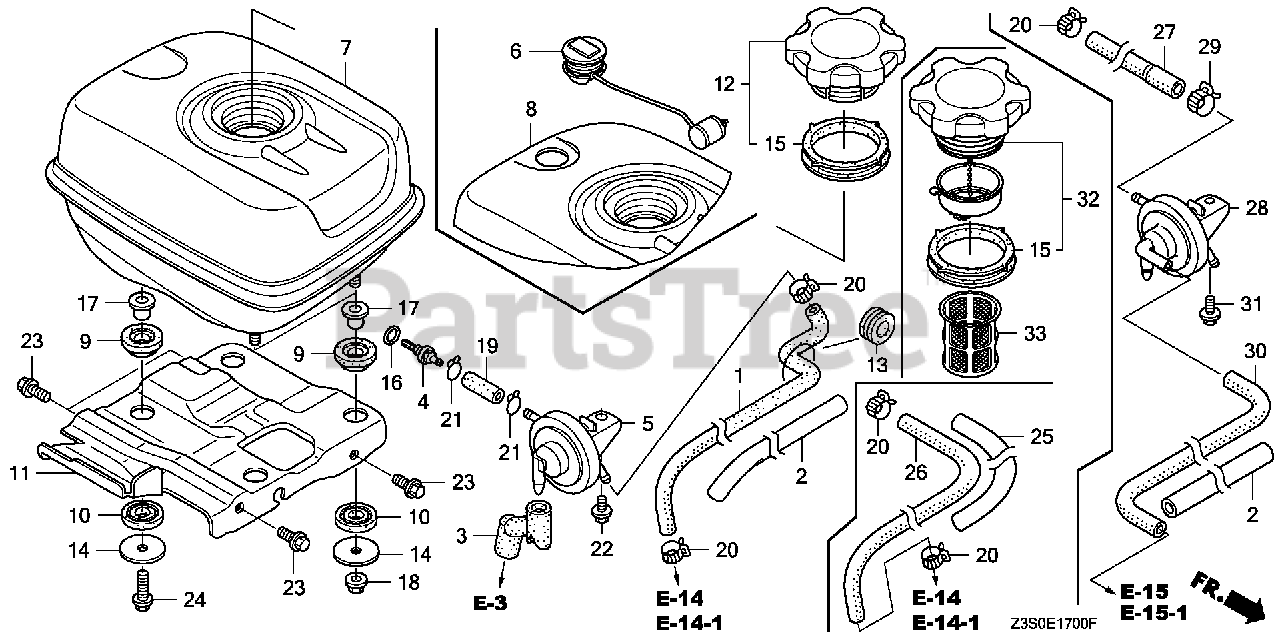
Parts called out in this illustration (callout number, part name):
1	TUBE, AUTO FUEL PETCOCK (FKM)
2	RUBBER, SUPPORTER
3	TUBE, DIAPHRAGM
6	GAUGE ASSY., FUEL
8	TANK, FUEL (GAUGE)
13	RUBBER, RR. FENDER CUSHION
20	CLIP, TUBE (D8)
28	PETCOCK ASSY., AUTO
30	TUBE, AUTO FUEL PETCOCK AIR CLEANER
31	BOLT, FLANGE (6X14)
